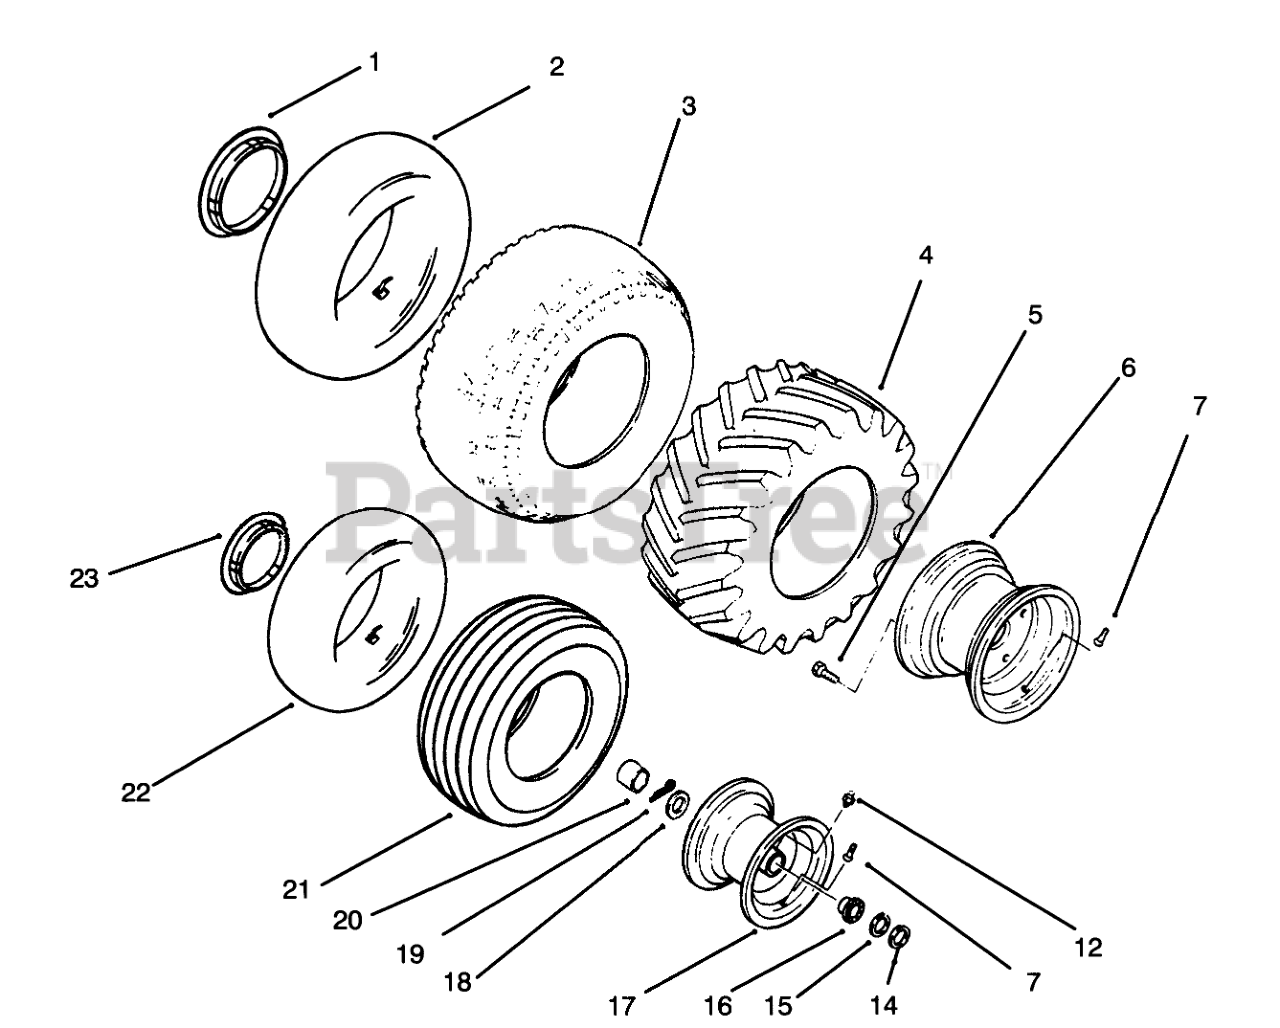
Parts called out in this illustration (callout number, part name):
1	12"-HUB CAP LOGO
2	TUBE-INNER
3	TIRE
4	Tire-Cleat, Rear
5	BOLT-LUG
6	WHEEL
7	VALVE
8	KEY-WOODRUFF
12	ZERK-GREASE
14	WASHER-SHIM
15	WASHER
16	BEARING-WHEEL
17	Wheel
18	WASHER WHEEL
19	PIN-COTTER
20	HUBCAP
21	Tire (16 x 6.5-8) 2-Ply -2 Wheel Axel
23	8"-HUB CAP LOGO
